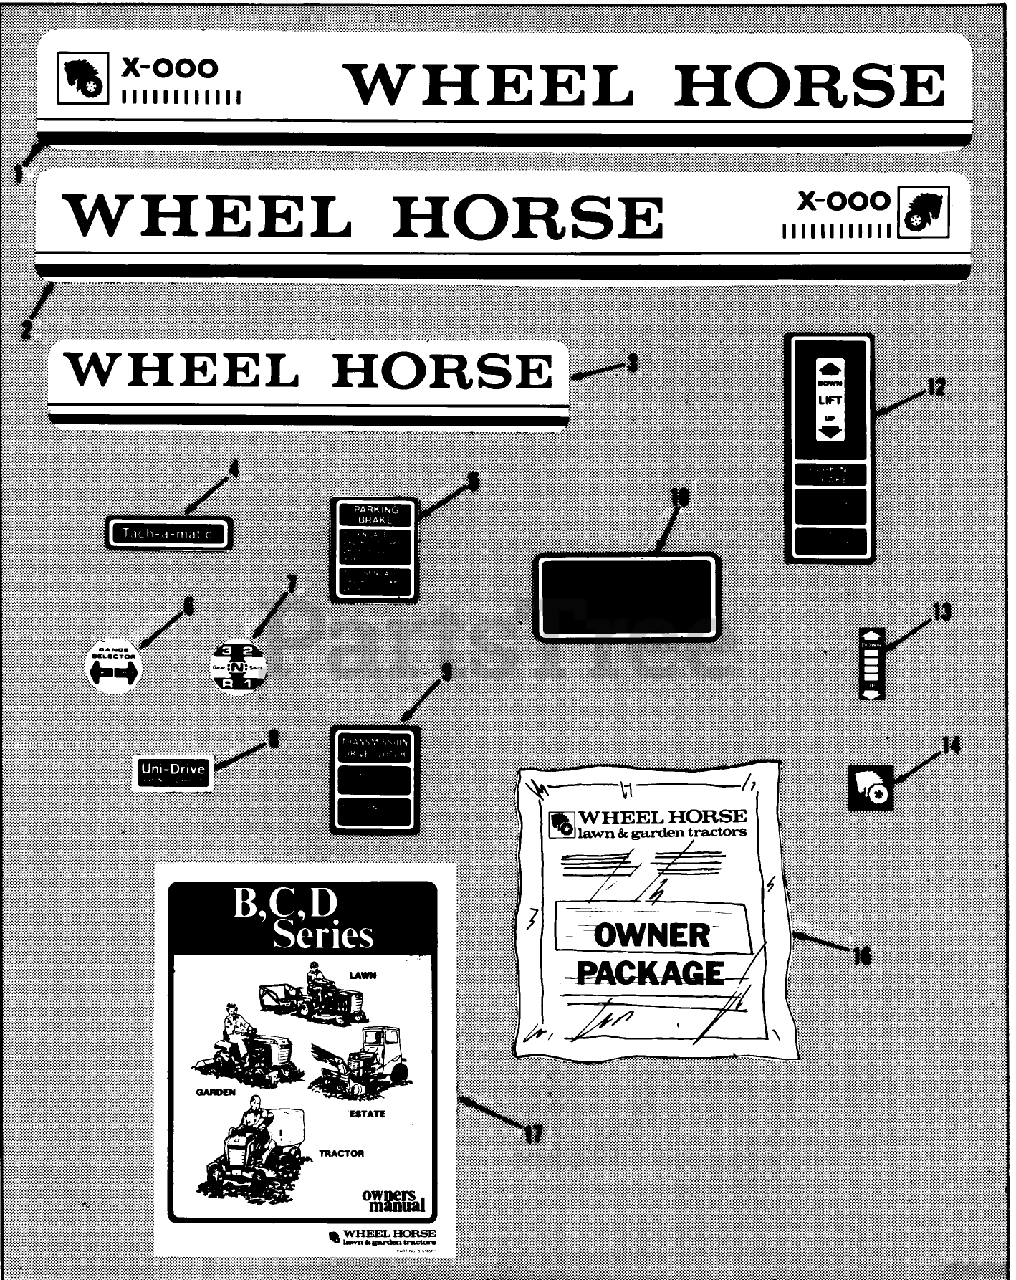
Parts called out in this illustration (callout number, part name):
1	ORDER 101637 R&L DECAL
2	Decal RH C-175 Twin Automatic
2	ORDER 101637 R&L DECAL
3	DECAL-REAR
5	DECAL-PARKING BRAKE
12	Decal-Parking Brake Lift
14	DECAL-LOGO
15	Decal-Taillight C-165, C-175 Twin Only
16	Loose Parts Package C-105, C-125, C-145 Only
16	Loose Parts Package C-165 Only
16	Loose Parts Package C-175 Twin Only
16	Loose Parts Package C-85 Only
17	Owner-s Manual
